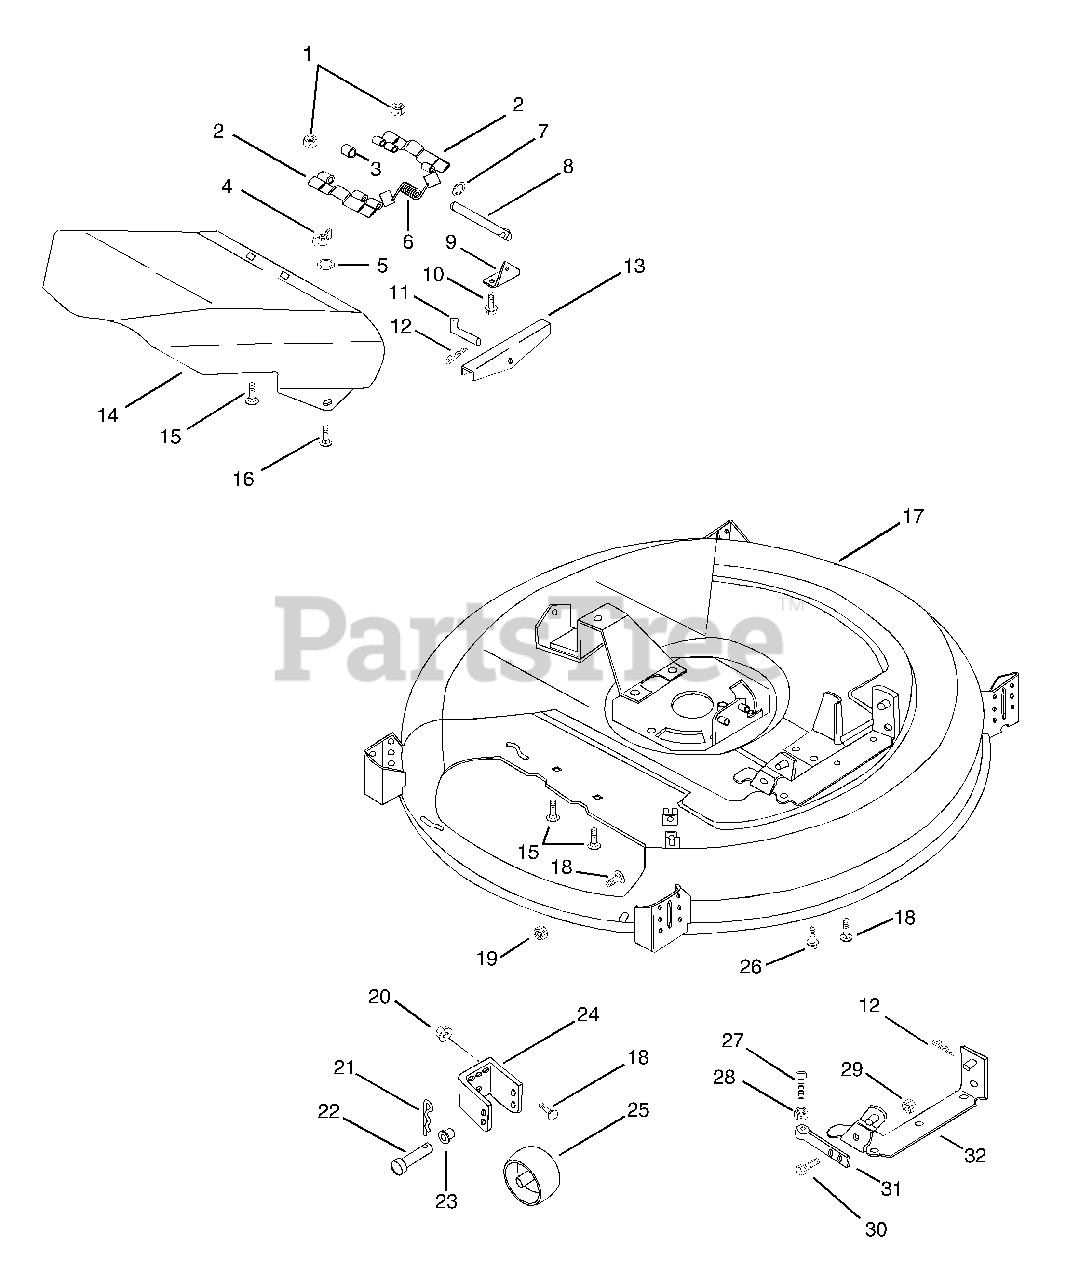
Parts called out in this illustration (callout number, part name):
1	@NUT-LK-CTR .25-20 YWZC
2	HINGE PLATE
3	BSHG-SLV .334 X .502 X 1.437
4	NUT-NYLK WING .312-18 YWZC
5	WSHR-FL-STL .328X.875X.062YWZC
6	SG-TORS .095X.50X 1.0
6	SG-TORS .090X.37X.63
7	RG-RTNG-EXT .312X.025
9	REAR MOUNTING BRACKET
10	@SCR-TAP .31-18X.50 HWH TR YWZ
11	CLEVIS PIN
12	PIN-HAIR INT .08X.38X1.42 YWZC
13	SWIVEL BRACKET
14	PAN CHUTE EXTENSION
14	28" DEFLECTOR W/DECALS
14	32" DEFLECTOR W/DECAL
15	@BLT-RDHDSQNK .25-20X.75 G5YZ
16	@BLT-RDHDSQNK .25-20X1.00 G5YZ
17	28"MOWER PAN W/DEFLECTOR&DECAL
17	28" MOWER PAN SERVICE ASSEMBLY
17	30"MOWER PAN W/DEFLECTOR&DECAL
17	30" MOWER PAN ASSEMBLY
17	32"MOWER PAN W/DEFLECTOR&DECAL
17	32" MOWER PAN ASSY RETROFIT
18	@BLT-RHDSSQNK .31-18X.62 G5YZ
19	@NUT-LK-CTR .31-18 YWZC
20	@NUT-SPNLK-FLG .312-18 YWZC
21	PIN-HAIR INT .08X.18X1.18 YWZC
22	PIN-CLEV .371X3.25 YWZC
23	BSHG-FLG .372X.500X.312X.625NY
24	ROLLER CLEVIS
25	ROLLER
26	@SCR-TAP .38-16X.50 HWH TR YWZ
27	@BLT-HEX .38-16X1.25 GR5 YWZC
28	NUT-HEX-JAM .375-16 YWZC
29	@NUT-LK-CTR .38-16 YWZC
30	@BLT-HEX .38-16X1.00 GR5 YWZC
31	ADJUSTING ARM
32	FRONT BRACKET 30"
